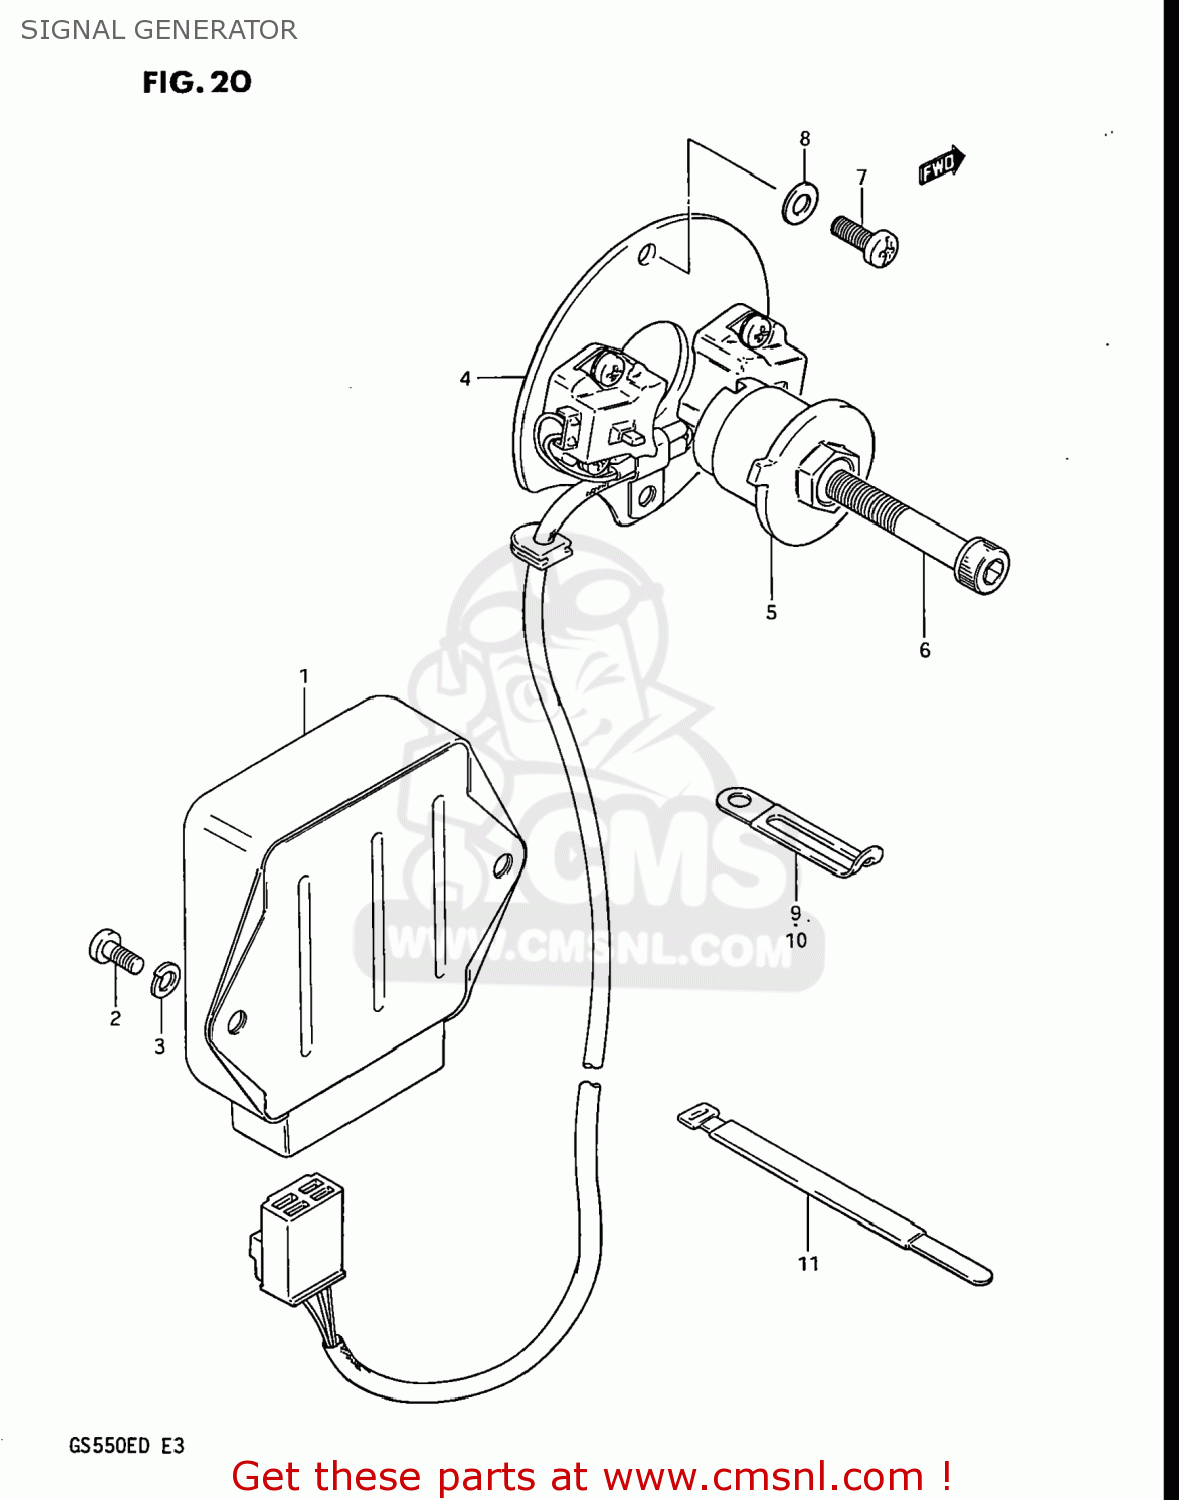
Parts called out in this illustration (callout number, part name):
1	IGNITER UNIT ASSEMBLY
2	SCREW 6X12
3	LOCK WASHER
4	GENERATOR ASSY,SIGNAL
5	ROTOR,SIGNAL
6	BOLT
7	SCREW(5X12)
8	WASHER
9	CLAMP L:35
10	CLAMP
11	CLAMP
